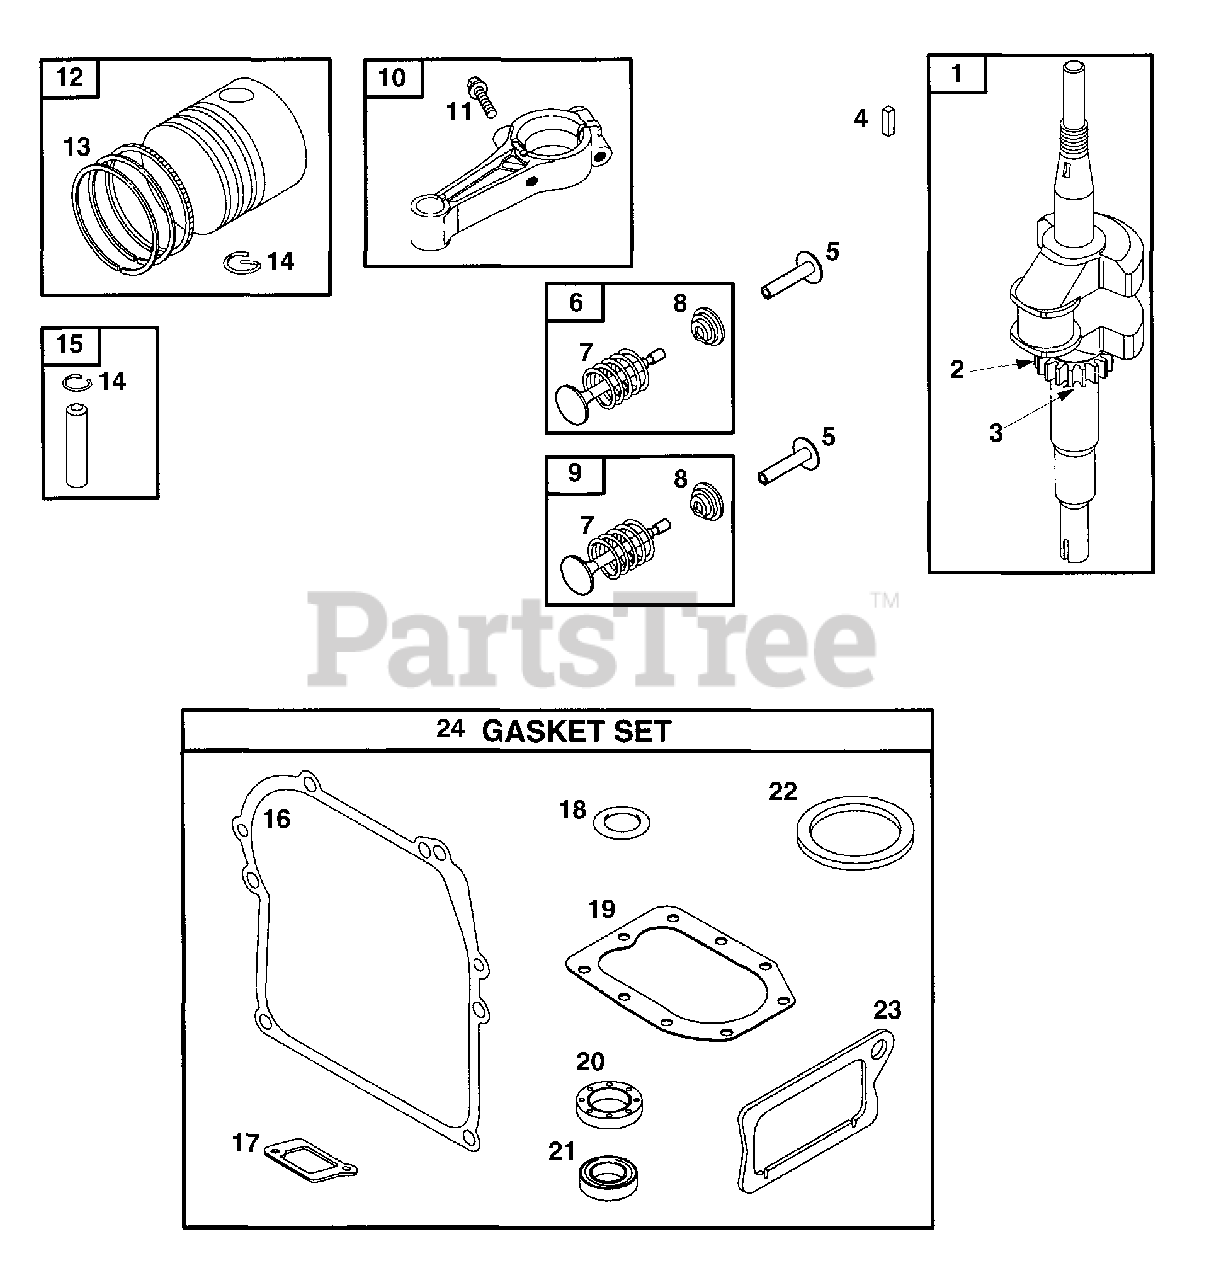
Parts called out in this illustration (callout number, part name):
1	Crankshaft
2	Timing Gear
3	Timing Pin
4	Flywheel Key
5	Valve Tappet
6	Intake Valve
7	Valve Spring
8	Valve Retainer
9	Exhaust Valve
10	Connecting Rod
11	Connecting Rod Screw
12	Piston Assembly
13	Ring Set (Standard)
14	Piston Pin Lock
15	Piston Pin (Standard)
16	Crankcase Gasket
17	Intake Gasket
18	O-Ring Seal
19	Cylinder Head Gasket
20	Oil Seal
21	Oil Seal
22	Air Cleaner Gasket
23	Breather Gasket
24	Gasket Set
